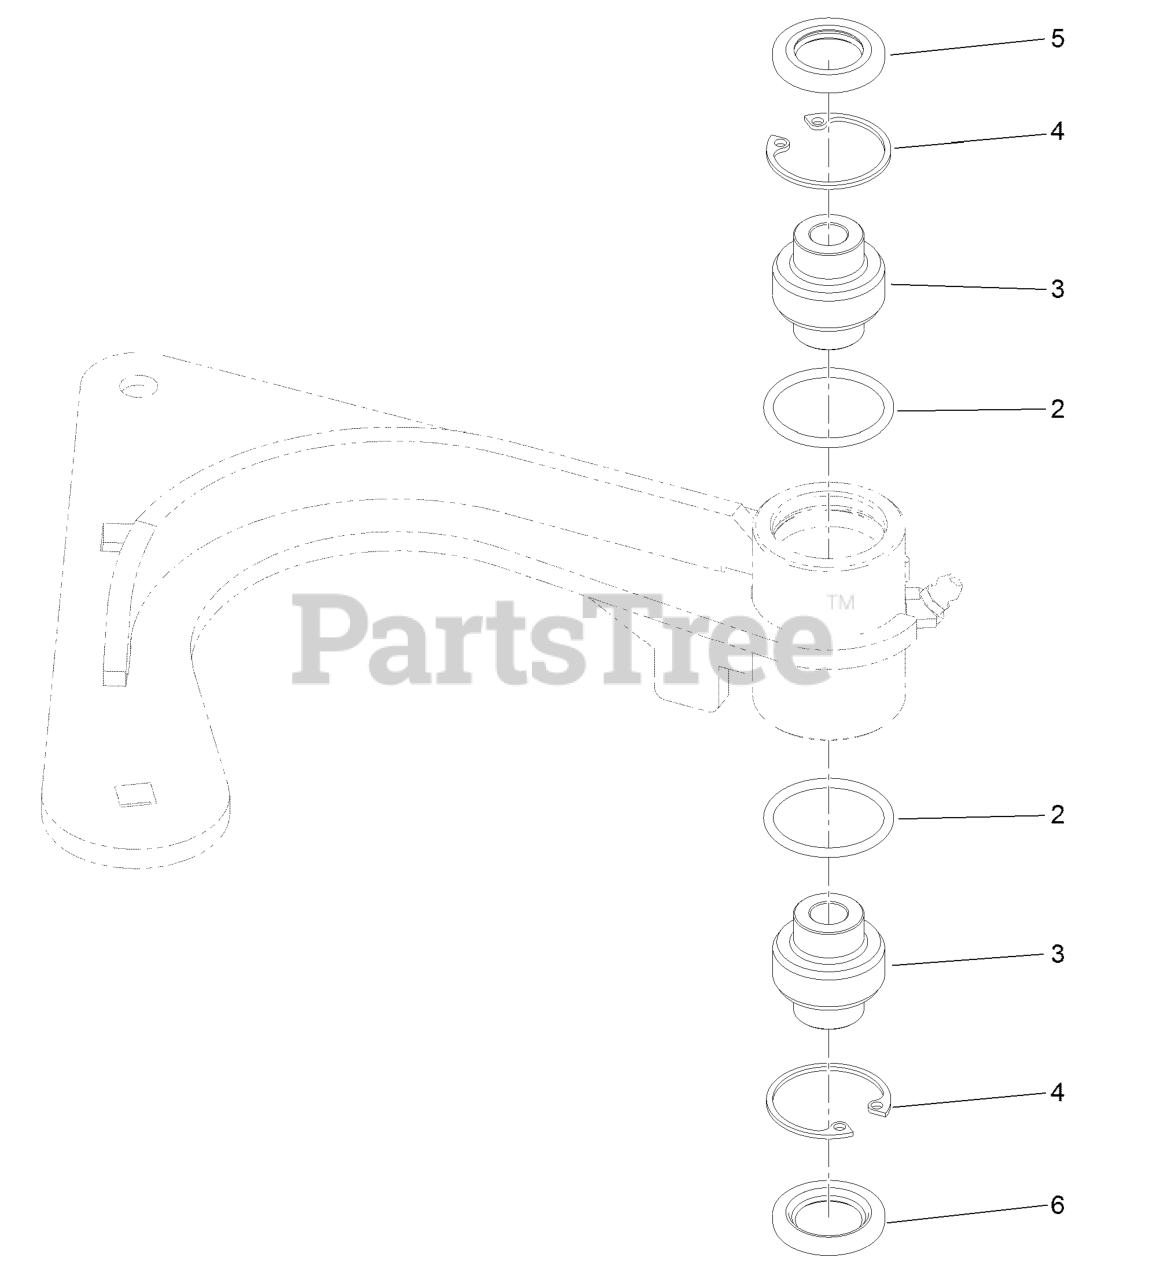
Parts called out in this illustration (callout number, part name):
3	Bearing-Spherical
4	Ring-Snap
5	Seal-Lip, Double
6	Seal-Lip, Single
